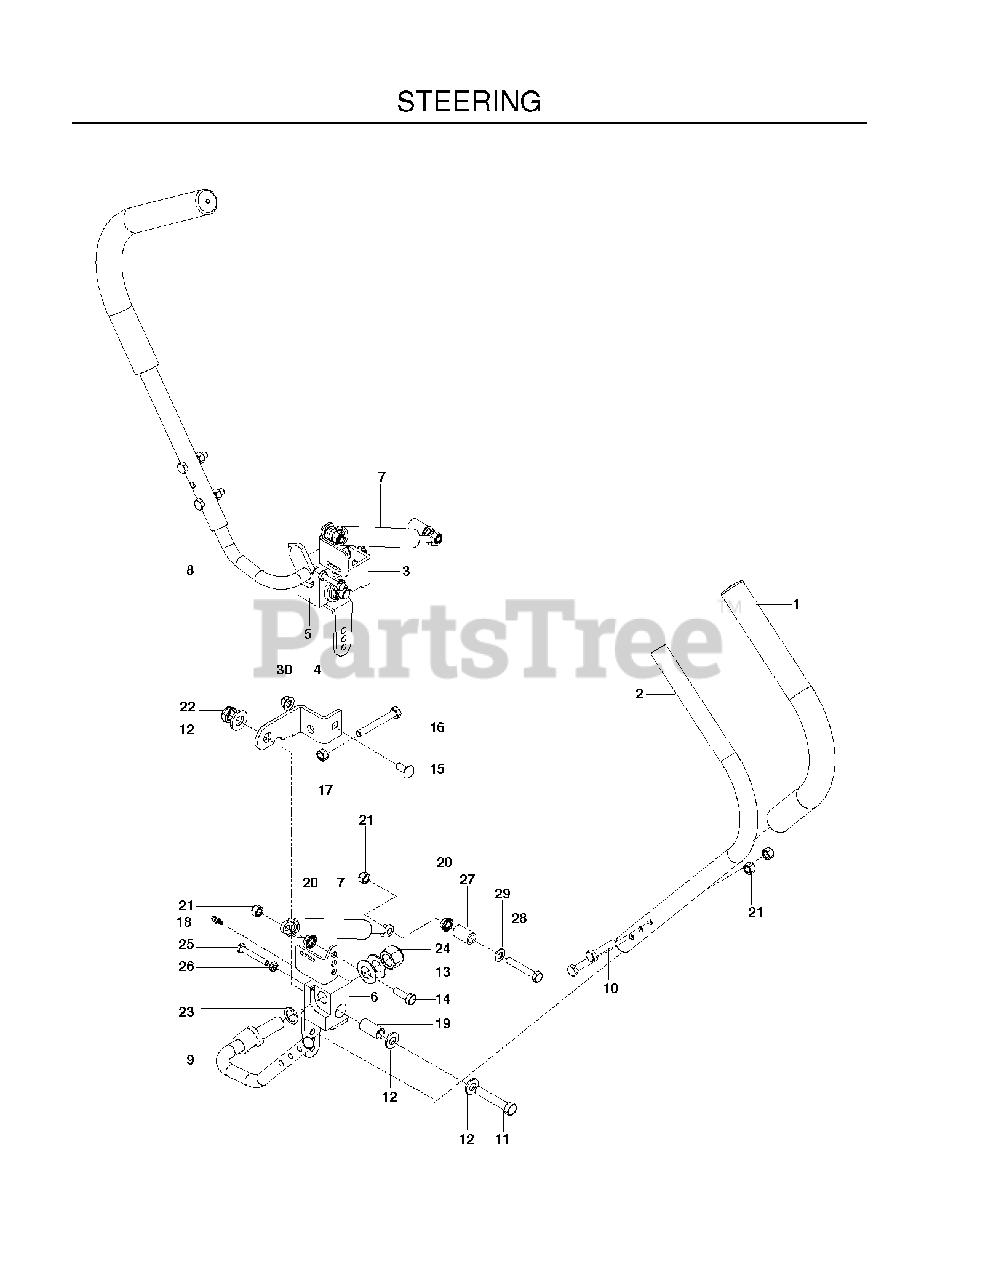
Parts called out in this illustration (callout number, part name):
2	LEVER UPPER
3	FORWARD STOP RH
4	FORWARD STOP LH
5	PIVOT RH (PLATED)
6	PIVOT LH (PLATED)
7	DAMPENER, DUAL ACTION
8	LEVER.PLATED.RH
9	LEVER PLATED LH
10	CAPSCREW 5/16 X 1/1/2 HEX HEAD
11	HCS 1/2C X 2 3/4
12	WASHER 1/2" FLAT
13	WASH 5/8 BEVELED DISC SPRING
14	HCS 5/16C X 1
15	BOLT 5/16C X 3/4" CARRIAGE
16	HCS 5/16-18 X 2 1/2 TPBLT
17	NUT 5/16C HEX
18	ZERK, 3/16, DRIVE IN
19	BUSHING
20	NUT 5/16C WHIZ
21	NUT 5/16 NYLOC
22	NUT 1/2-13 HEX JM NYL
23	WASHER-.626IDX.056TK
24	NUT 5/8-11 NYLOC
25	BOLT 1/4C X 1 3/4
26	NUT 1/4-20 JAM
27	BUSHING
28	HCS 5/16-18X2
29	FLAT WASHER 5/16 SAE
30	5/16-18 NYLOC FLANGE NUT
